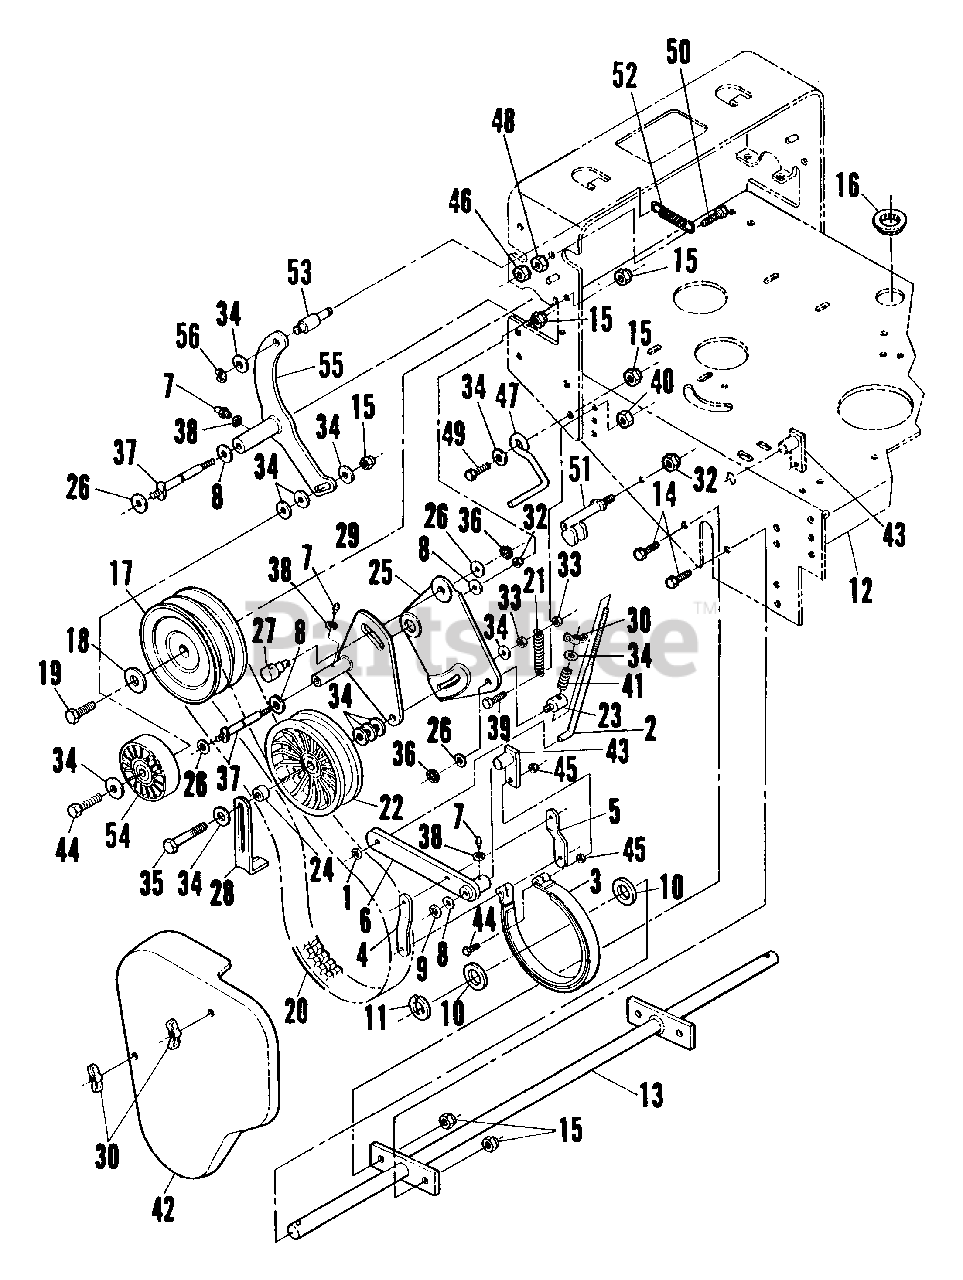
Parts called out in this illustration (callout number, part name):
1	WHEEL, Retainer, 3/8"
2	ROD, Brake
3	BAND, Brake, 6"
4	PLATE, Brake Link
5	LINK, Brake
6	LEVER, Brake, R.H.
7	FITTING, Grease, 1/4-28 Straight
8	BUSHING, Machinery, 5/8"
9	RETAINER, 5/8" Bolt
10	BUSHING, Machinery, 1"
11	RING, 1" External Retaining
12	WELDMENT, Rear Deck
13	WELDMENT, Axle
14	SCREW, 3/8-16 x 1" Hex Head Cap, Grade 5
15	NUT, 3/8-16 Hex Nyloc
16	SNAP BUSHING
17	PULLEY, Output
18	WASHER, 3/8" Cone
19	SCREW, 3/8-24 x 3/4" Hex Head Cap, Grade 5
20	BELT, Traction
21	SPRING, Traction
22	PULLEY, Idler
23	SWIVEL, Brake Link
24	SPACER, Guide
25	ARM, Idler Bracket, R.H.
26	WASHER, 5/16" Flat
27	SWIVEL, Traction
28	GUIDE, Belt Forward
29	ARM, Traction, R.H.
30	WING NUT, 3/8-16 Nyloc
32	NUT, 3/8-24 Hex Center Lock
33	NUT, 3/8-16 Hex Top Lock
34	WASHER, 3/8" Flat
35	SCREW, 3/8-16 x 3-1/2" Hex Head Cap, Grade 5
36	RETAINER, Ring
37	STUD, Fender Mt.
38	WASHER, 1/4" Internal Tooth Lock
39	SHOULDER BOLT, 5/16-18
40	NUT, 5/16-18 Hex Nyloc
41	SPRING, Bracket Link
42	FENDER, R.H.
43	WELDMENT, Brake Stud
44	BOLT, 3/8-16 x 2" Hex Head, Grade 5
45	NUT, 3/8-16 Hex
46	NUT, 1/4-20 Hex Center Lock, Grade B or 5
47	BELT GUIDE, Traction
48	NUT, 1/4-20 Hex
49	BOLT, 3/8-16 x 1-1/4" Hex, Grade 5
50	SCREW, 1/4-20 x 1" Hex Head Cap, Grade 5
51	SCRAPER, Wheel
52	SPRING
53	SWIVEL, Reverse
54	PULLEY, Idler
55	ARM, Reverse, R.H.
56	RING, 3/8" External Retaining
